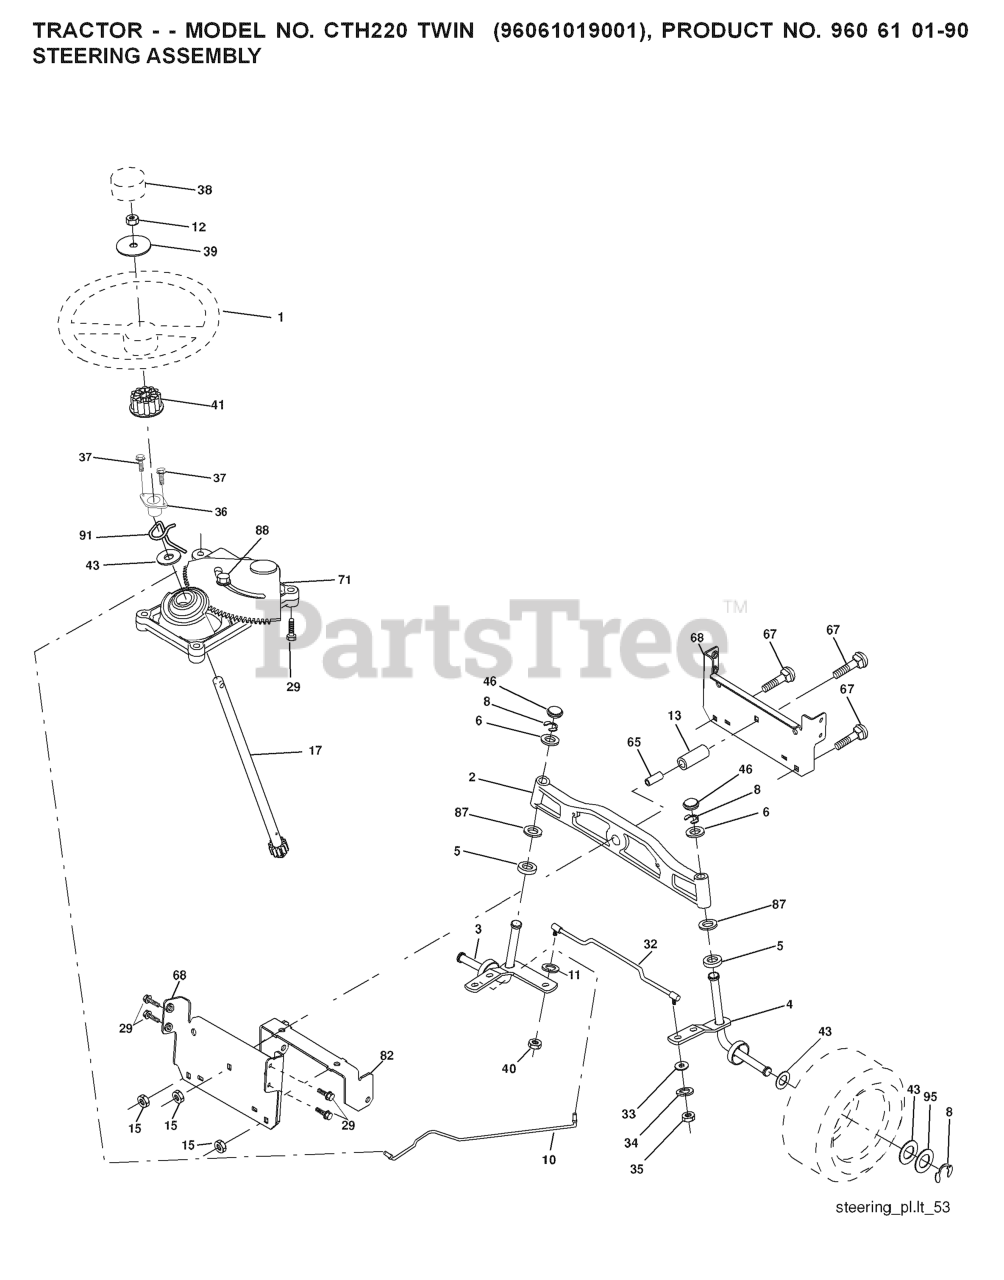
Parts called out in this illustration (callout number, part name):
1	STEERING WHEEL
2	AXLE ASSY FRONT
3	SPINDLE.ASM.LH.15"TIRES
4	SPINDLE.ASM.RH.15"TIRES
5	THRUST WASHER
10	DRAGLINK.15".TIRES.2001
11	WASHER, LOCK 3/8
12	NUT.HEX.1/2-20
13	TUBE, PIVOT AXLE
15	NUT
17	SHAFT ASM STRG
29	SCREW, 3/8-16X3/4
32	TIE ROD
33	WASHER M
34	WASHER.LOCK.HVY.HLCL.SPR.5/16
35	NUT, CROWNLOCK
36	BUSHING, STRG. BLK
37	SCREW.TT.#10-32X.5.3/8.FLANGE
38	INSERT.CAP.STRG.WH.GRAY
39	WASHER 9/16"ID, 2 3/8"OD
40	NUT CROWNLOCK 3/8-24
41	ADAPTER, WHEEL STNG..
46	CAP.SPINDLE.BLACK
65	SPACER BRACE AXLE
67	BOLT CARRIAGE
68	BRACE.AXLE.15"TIRES
71	STEERING ASM
82	BRACKET.SUSP.CHASSIS.FRONT.15
87	WASHER, FLAT .781 X 1 1/2"
88	BOLT, SHOULDER 7/16-20
91	CLIP.STEERING
95	WASHER.HARDENED
